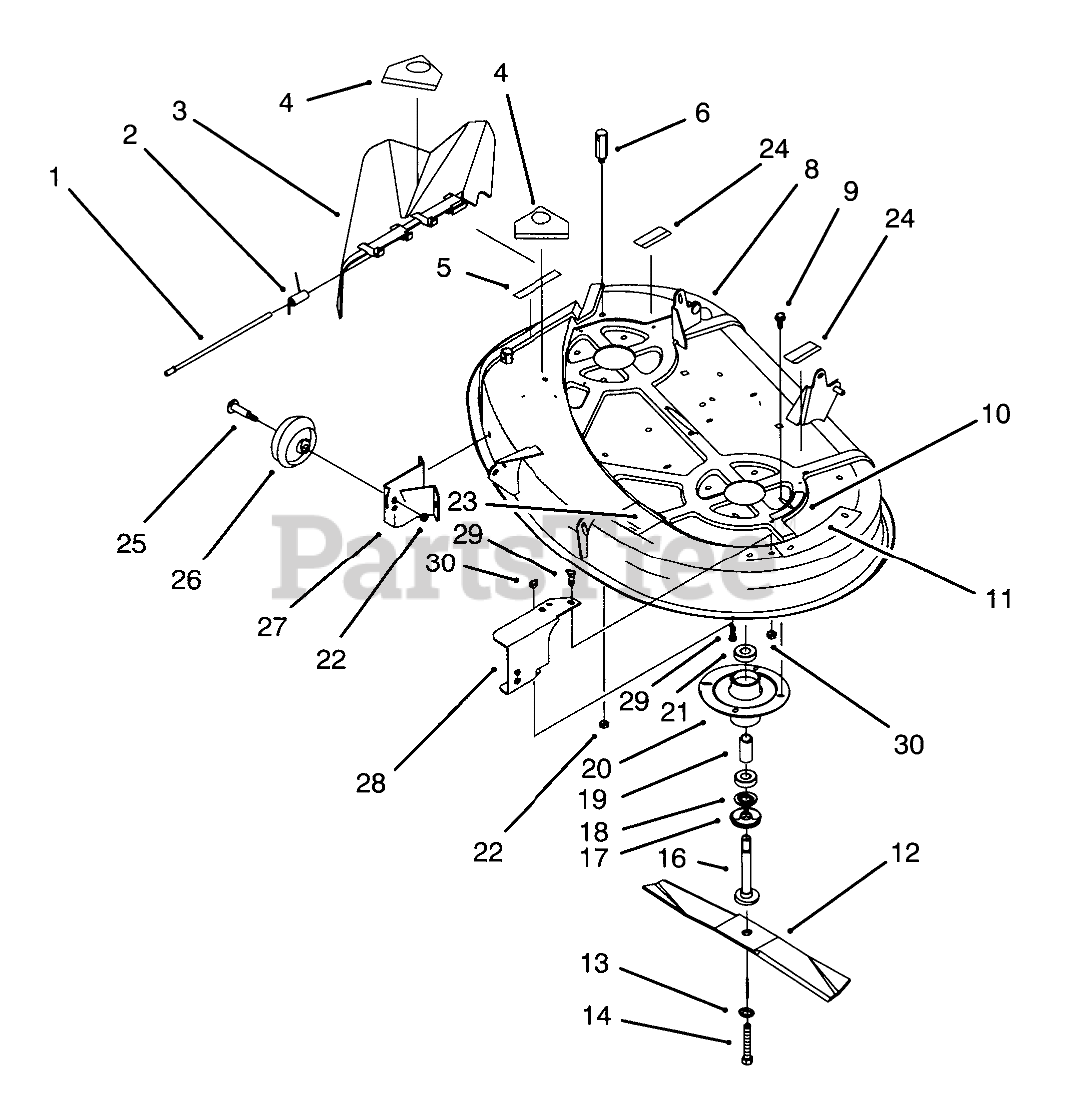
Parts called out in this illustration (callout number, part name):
1	ROD-HINGE DEFLECTOR
2	SPRING
3	Deflector-Deck
4	DECAL-DANGER
5	DECAL-DANGER, DEFLECTOR
6	REAR PIVOT POST (PLTD)
8	Deck-38"
9	SCREW-TAPTITE
10	DECAL-DANGER, SHIELD
11	DECAL-DANGER
12	Blade
13	WASHER-BELLEVILLE
14	SCREW-HH
16	SHAFT-SPINDLE
17	SHIELD-BEARING
18	SPACER
19	SPACER
20	HOUSING-SPINDLE
21	BEARING-BALL
22	NUT-LOCK, NI
23	Decal-Routing
24	DECAL-WARNING
25	SCREW-SHOULDER, HWH
26	WHEEL-GAGE
27	Bracket-R.H.
28	LH WHEEL DECK BRKT
29	SCREW-HH
30	NUT-LOCK, NI
